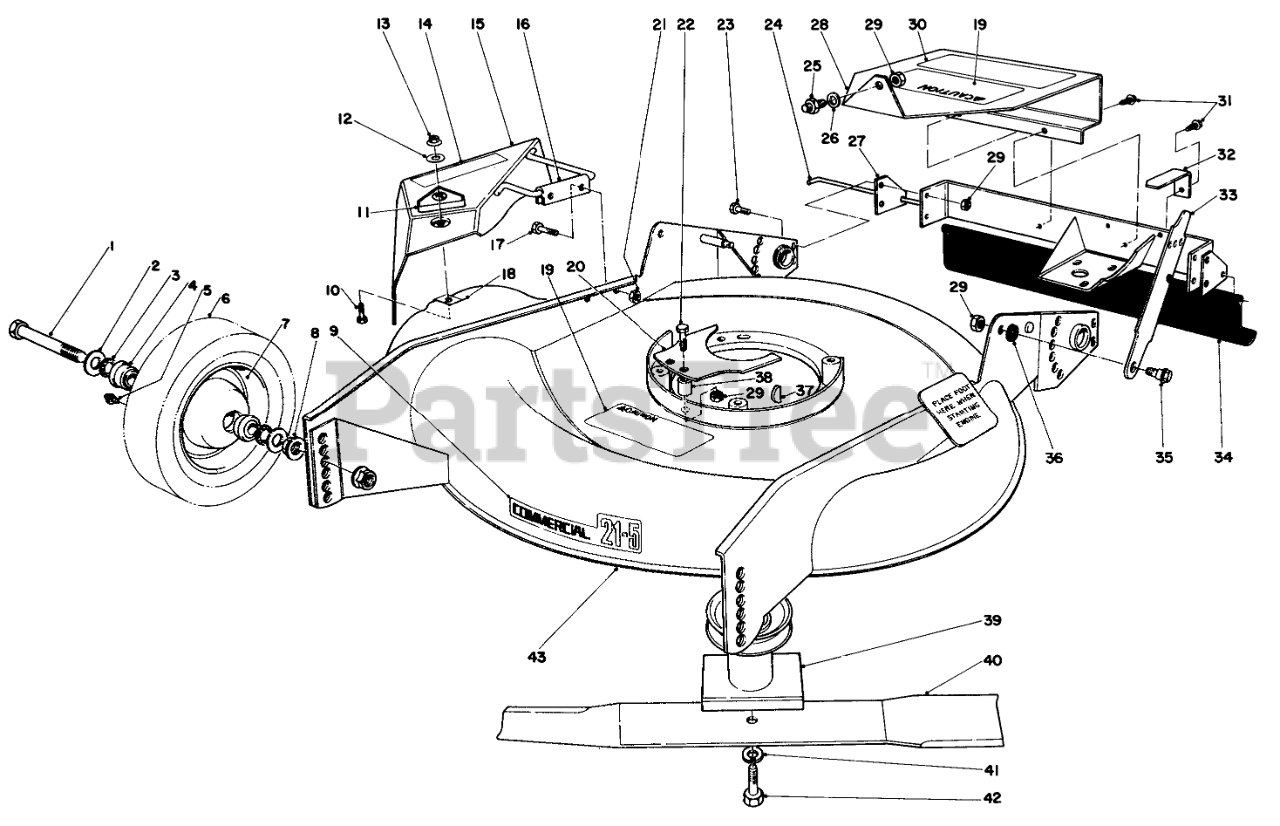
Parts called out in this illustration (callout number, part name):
1	SCREW-HH
2	WASHER-FLAT
3	FELT WASHER
4	BEARING-BALL
5	FITTING-GREASE
7	Wheel & Tire Assembly (Incl. Ref. #44)
8	NUT-HF
9	Decal-Commercial 21-5
10	SCREW-HH
11	DECAL-DANGER
12	WASHER-FLAT
13	NUT-LOCK, HHF
14	Decal
15	Deflector (Incl. Ref. #11 & 14)
16	Hinge-U Bracket
17	SCREW-HH
18	NUT-SPEED
19	DECAL SAF INST
20	Belt Guide-Front
21	NUT-LOCK
22	SCREW-HH
23	SCREW-HH
24	SAFETY SHIELD ROD
25	Head Bolt Stud
26	Washer
27	Bracket-Safety Shield
28	Shroud (Incl. Ref. #19 & 30)
29	Nut
30	Decal
31	Screw
32	Belt Guide-Rear
33	HANDLE LATCH
34	Rear Safety Shield
35	SCREW-SHOULDER
36	SPACER
37	KEY-WOODRUFF
38	BELT GUIDE SPACER
39	Yoke Bushing
40	BLADE
41	WASHER-LOCK
42	Place Bolt
43	Housing
